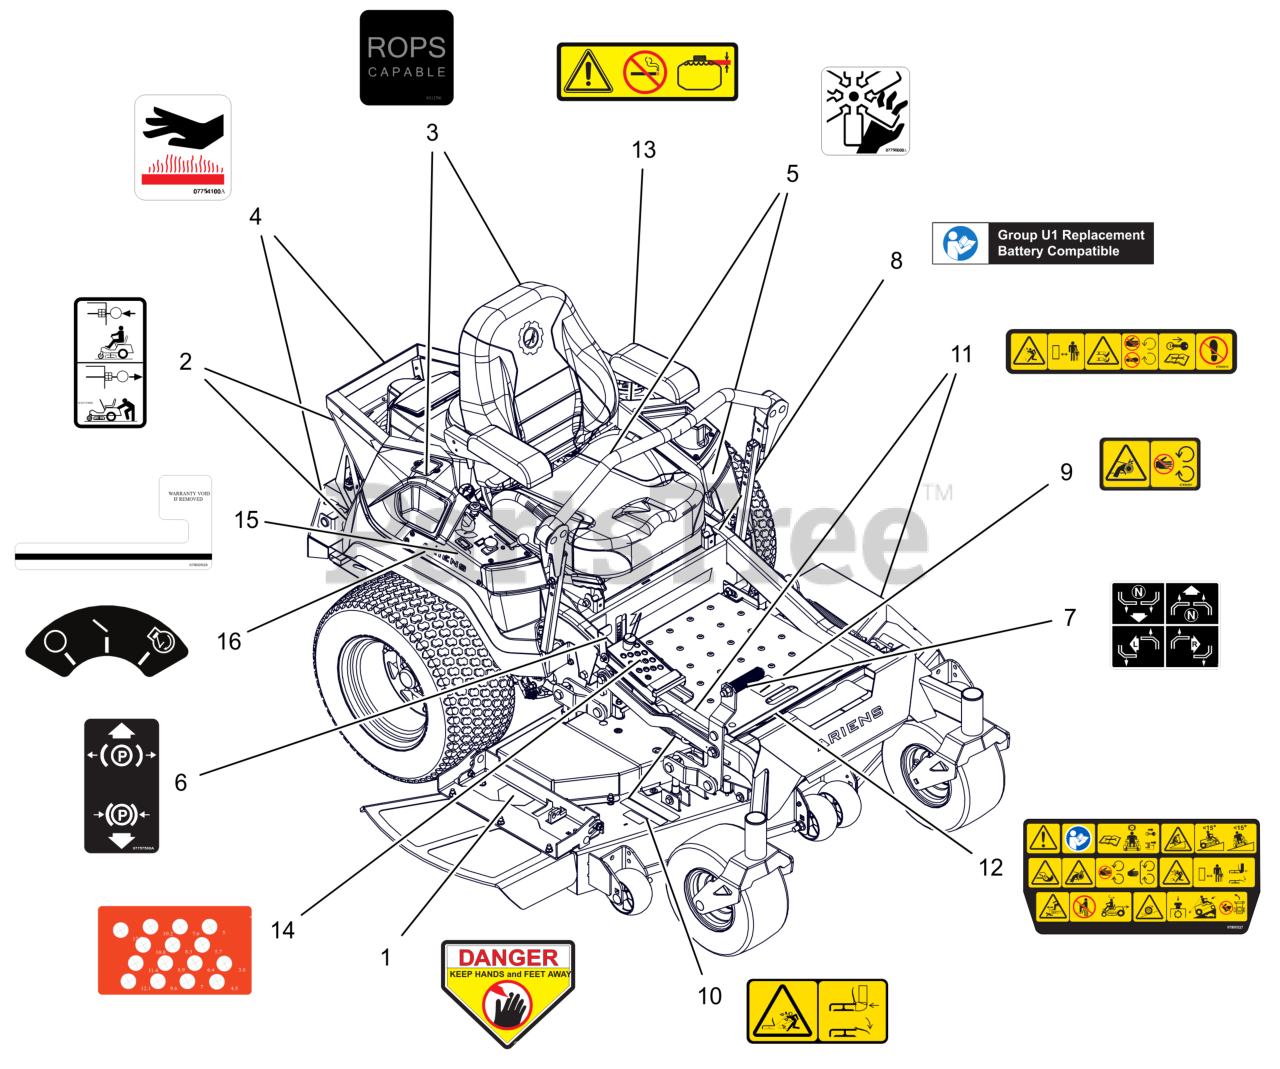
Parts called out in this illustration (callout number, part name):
1	DECAL, DANGER
2	DECAL, TRANSMISSION DISCONNECT
3	DECAL, ROPS LOCATION
4	DECAL, HOT SURFACE
5	DECAL, DANGER FAN
6	DECAL, PARKING BRAKE LEVER
7	DECAL, INSTRUCTIONAL-STEERING
8	DECAL, U1 BATTERY REPLACEMENT
9	DECAL, SAFETY - GUARDING
10	DECAL, SAFETY - DECK GUARDING
11	DECAL, DECK SAFETY
12	DECAL, MAIN SAFETY
13	DECAL, FUEL WARNING
14	DECAL, APEX HOC METRIC
15	DECAL,HOURMETER - SECURITY
16	DECAL, KEYSWITCH
